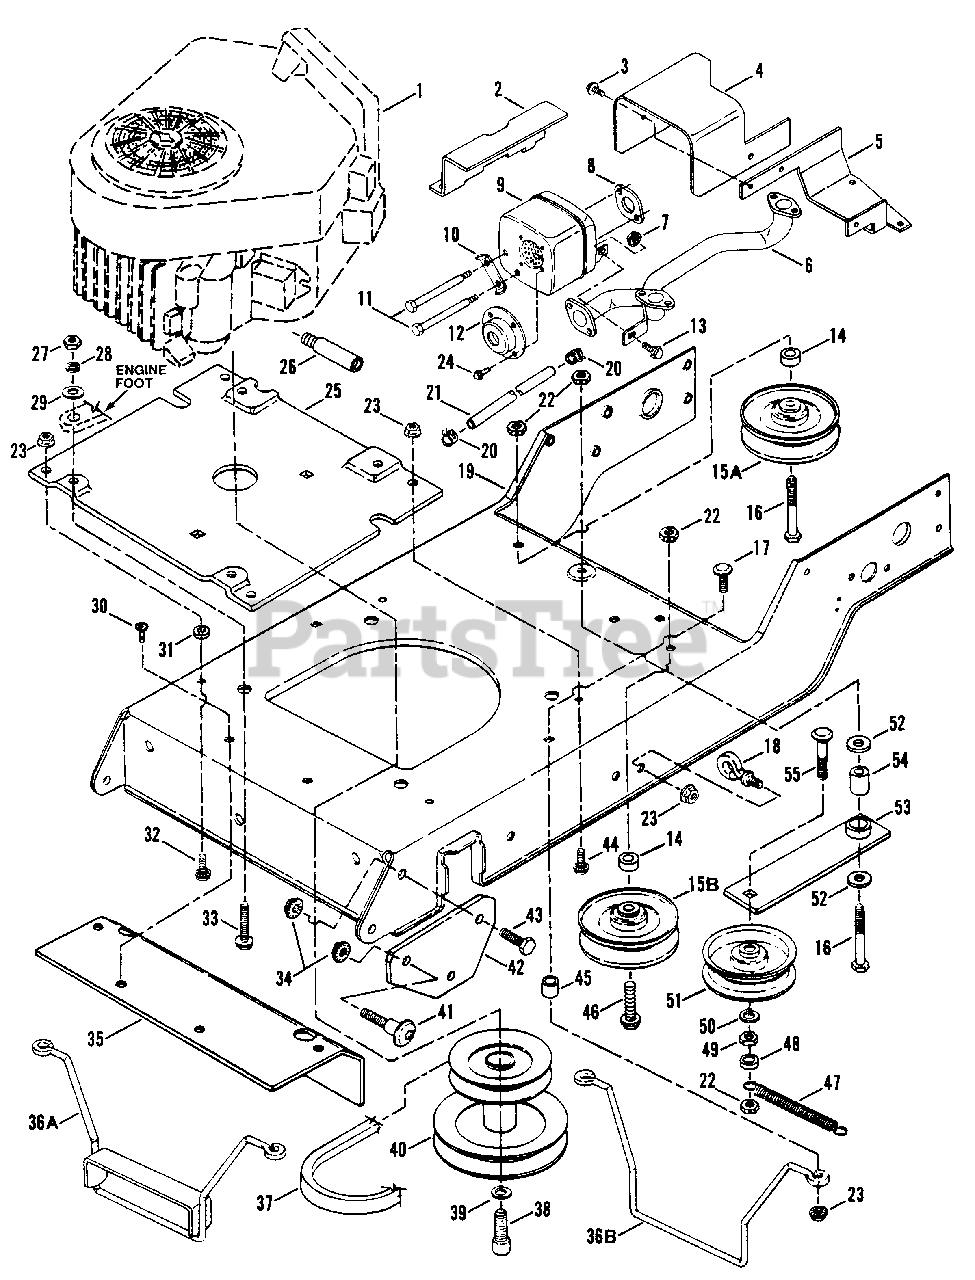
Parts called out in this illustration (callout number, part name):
2	HEAT SHIELD, Manifold
3	SCREW, 1/4-20 x 3/8" Self-Tapping
4	HEAT SHIELD, Muffler (No longer available, try using 7034761)
5	SUPPORT, Heat Shield
6	MANIFOLD, Exhaust (No longer available, try using 7041742)
7	NUT, 1/4-20 Hex Flange Lock
8	GASKET, Exhaust
9	MUFFLER
10	LOCK, Screw
11	BOLT, 5/16C x 4.1" Hex Head Cap
12	DEFLECTOR, Direct Out
13	SCREW, 1/4-20 x 1/2" Hex Flange, Self-Tapping
14	SPACER .750 OD x .390 ID x .5 L
15A	PULLEY, Idler, 3.56" O.D.
15B	PULLEY, Idler, 4" O.D.
16	BOLT, 3/8-16 x 2 1/4" Hex Head
17	BOLT, 5/16-18 x 3/4" Short Neck Carriage
17	BOLT, 5/16-18 x 1 1/2" Carriage (38" Models Only)
18	EYE-BOLT
19	BASE, Engine
20	CLAMP, Fuel Line .490 x .31
21	LINE, Fuel 10.5" x 1/4" ID
22	NUT, 3/8-16 Hex Center Lock
23	NUT, 5/16-18 Hex Flange Lock
24	SCREW, 8/18 x 1/2" Hex Head, Self-Tapping
25	SUB-PLATE, Brigg's Engine
26	OIL DRAIN, Pipe 3.5" Long 1/2" ID .375 NPF (No longer available)
27	NUT, 5/16-18 Hex
28	WASHER, 5/16 Split Lock
29	WASHER, 5/16 Flat
30	SCREW, 5/16-18 x 7/8" Truss Head (Torx)
31	RETAINER, 5/16 Bolt
32	BOLT, 5/16-18 x 1" Hex Flange Lock
33	SCREW, 5/16-18 x 1 1/2" Hex Head Cap
34	NUT, 3/8-16 Hex Flange Lock
35	SUPPORT, Axle (No longer available)
36A	GUIDE, Belt (38" Models Only)
36B	GUIDE, Belt (42" & 48" Models)
37	V-BELT, Traction Drive A113.6
38	SCREW, 7/16-20 x 1" Hex Cap, Socket Head
39	WASHER, 7/16 Split Lock
40	ASSEMBLY, Engine Pulley
41	SCREW, 3/8-16 x 1 1/4" Shoulder (Torx)
42	BRACKET, Hood
43	SCREW, 3/8-16 x 3/4" Hex Head Cap
44	BOLT, 5/16-18 x 3/4" Hex Flange Lock
45	SPACER, .81 OD X .48 ID x .5 L (38" Models Only)
46	BOLT, 3/8-16 x 1 3/4" Hex Flange Lock
47	SPRING, Idler Arm
48	SPACER .623 OD x .38 ID x .25 L
49	NUT, 3/8-16 Hex
50	WASHER, 3/8 Split Lock
51	PULLEY, Idler, 3 3/4" O.D.
52	WASHER, 3/8" Flat
53	ARM, Idler
54	BUSHING, Idler Arm .750 OD x .406 ID x .75 L
55	BOLT, 3/8-16 x 2 1/2" Short Neck Carriage
